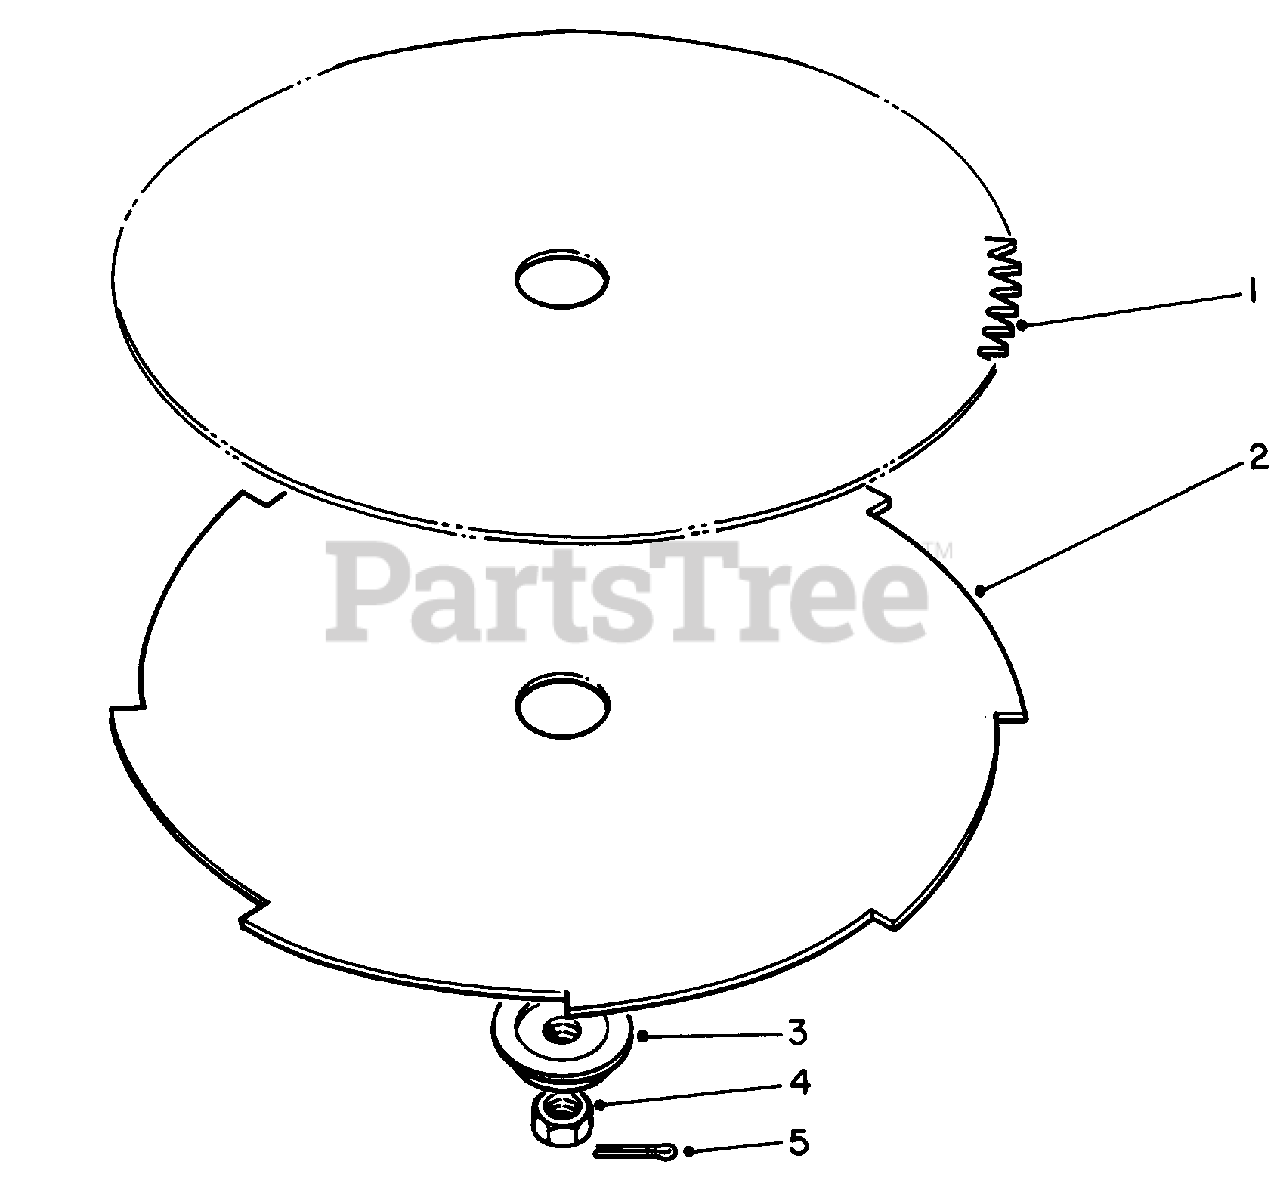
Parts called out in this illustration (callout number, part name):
1	8" Dia. Blade (80 Tooth)
2	8" Dia. Blade (8 Tooth)
3	Adapter-Blade
5	Cotter Pin
